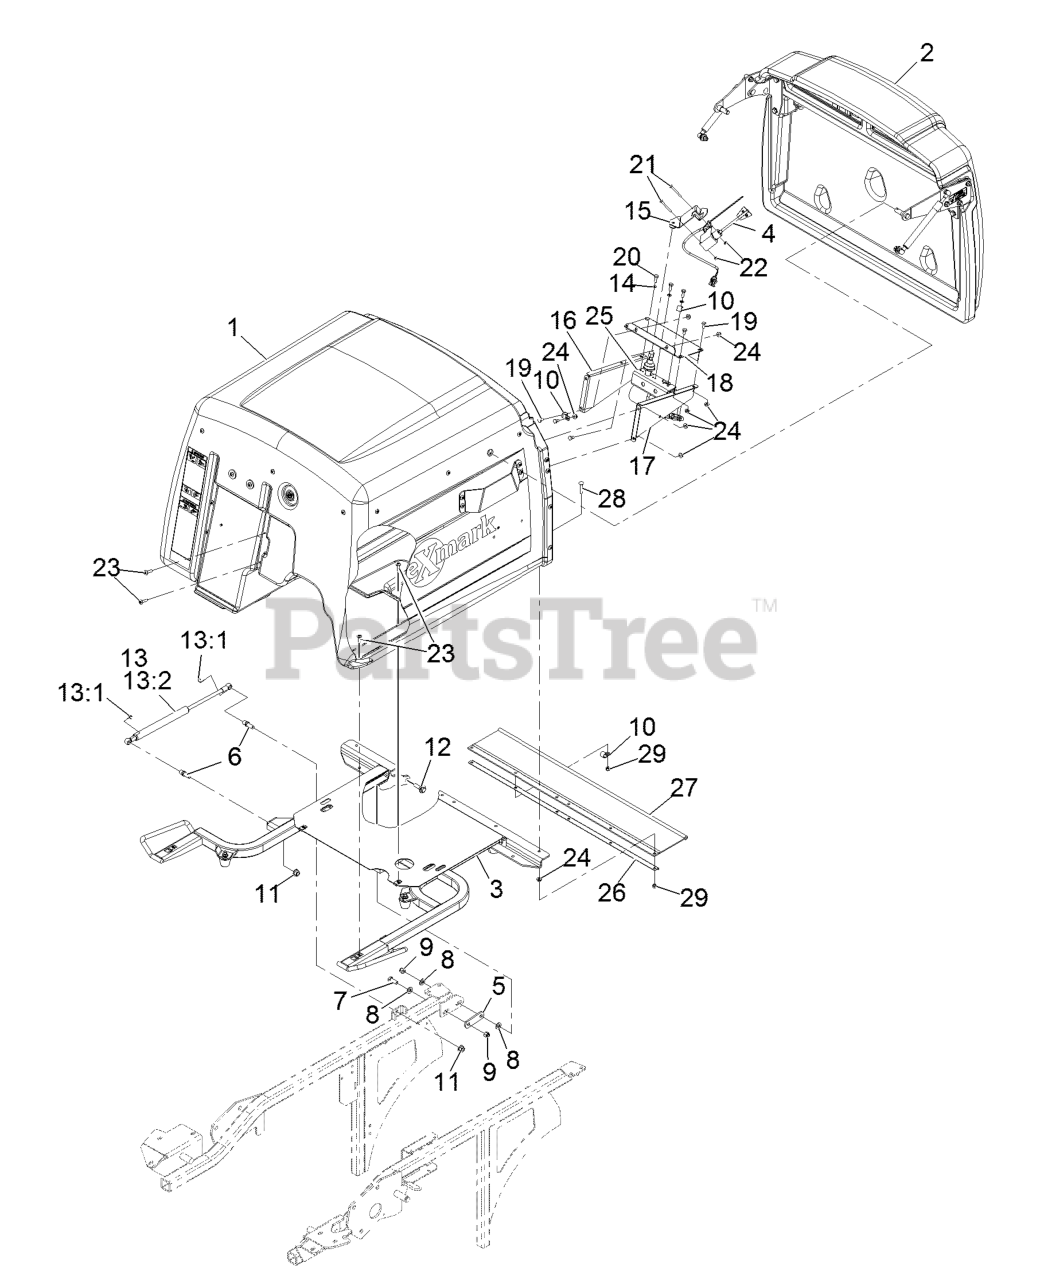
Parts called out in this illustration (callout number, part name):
1	ASM,HOPPER
2	ASM,DOOR HOPPER
3	HOPPER FRAME ASM
4	ASM,FILL SENSOR
5	ARM-LIFT, DECK
6	STUD-BALL
7	SCREW-HH
8	WASHER-FLAT
9	NUT-LOCK, NI
10	CLIP-LOOM
12	SCREW-SHOULDER, HWH
13	DAMPER KIT
13:1	CLIP-RETAINER
13:2	SHOCK-COMPRESSION, GAS
14	WASHER-SPRING
15	MOUNT-SWITCH
16	BRACKET-DRIVE MOTOR, LH
17	BRACKET-DRIVE MOTOR, RH
18	PLATE-SWITCH
19	SCREW-HH
20	SCREW-HH
21	SCREW-PPH
22	NUT-LOCK, NI
23	SCREW-TTH
25	KIT,FILL SENSOR MOTOR
26	CHANNEL-FRAME, HOPPER
27	DEFLECTOR-GRASS
28	SCREW-CARR
29	NUT-LOCK, NI
